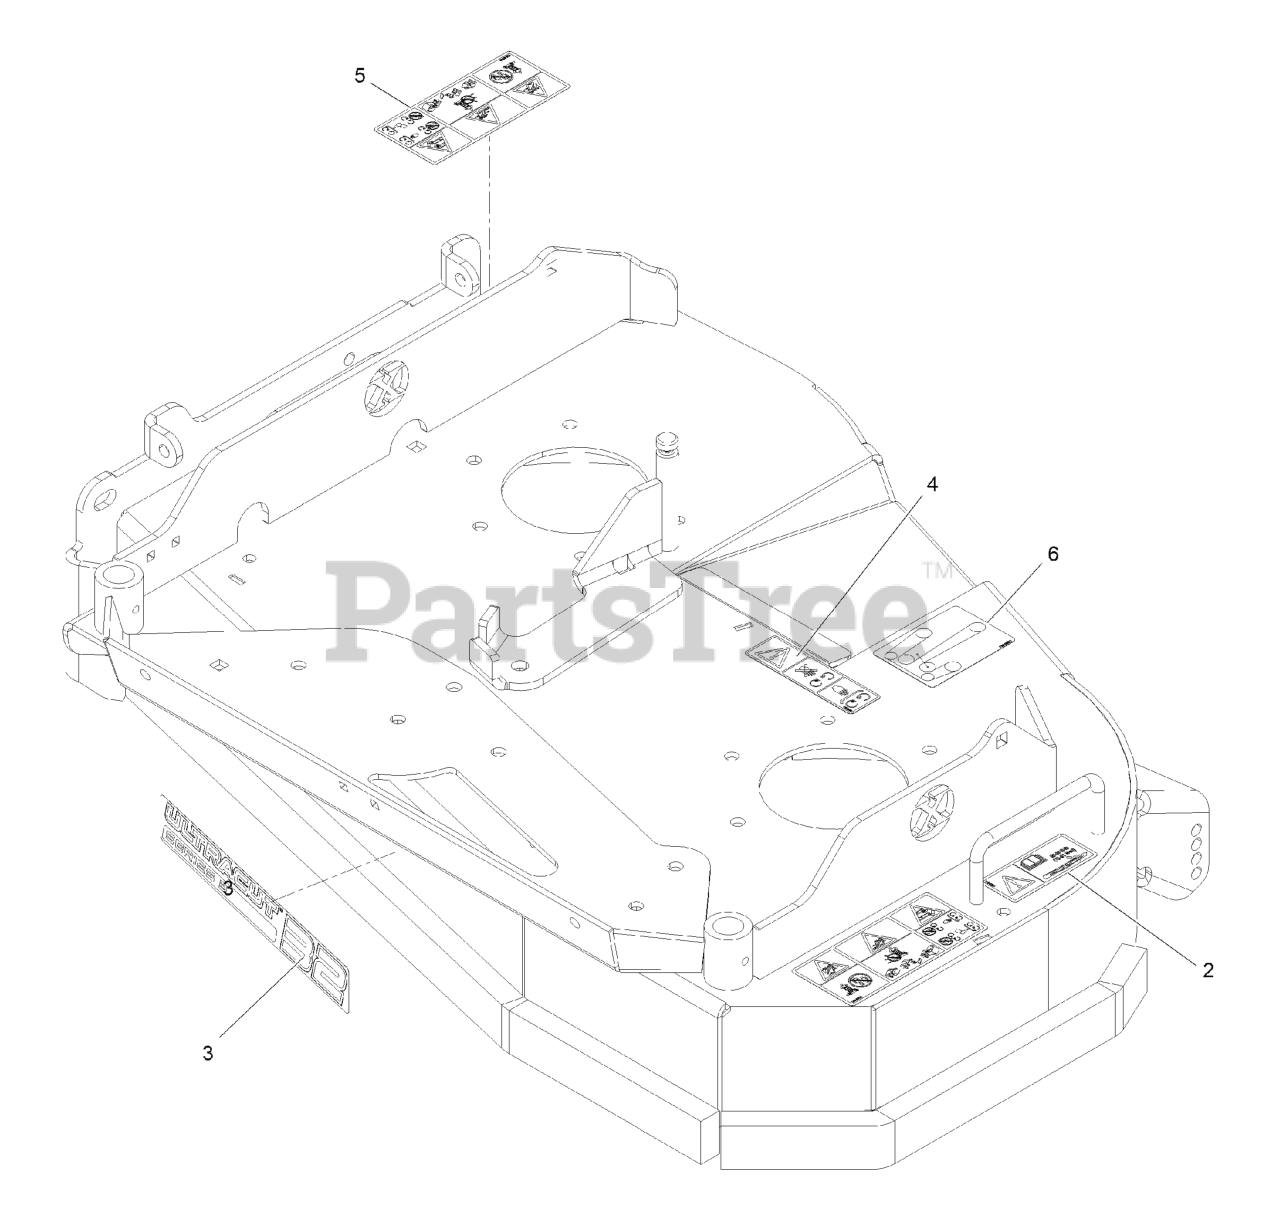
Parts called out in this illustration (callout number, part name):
2	DECAL-TORQUE, BOLT
3	DECAL-ULTRACUT 32-SERIES 3
4	DECAL-COVER, MISSING
5	DECAL-WARNING THROWN OBJ
6	DECAL-BELT ROUTING
